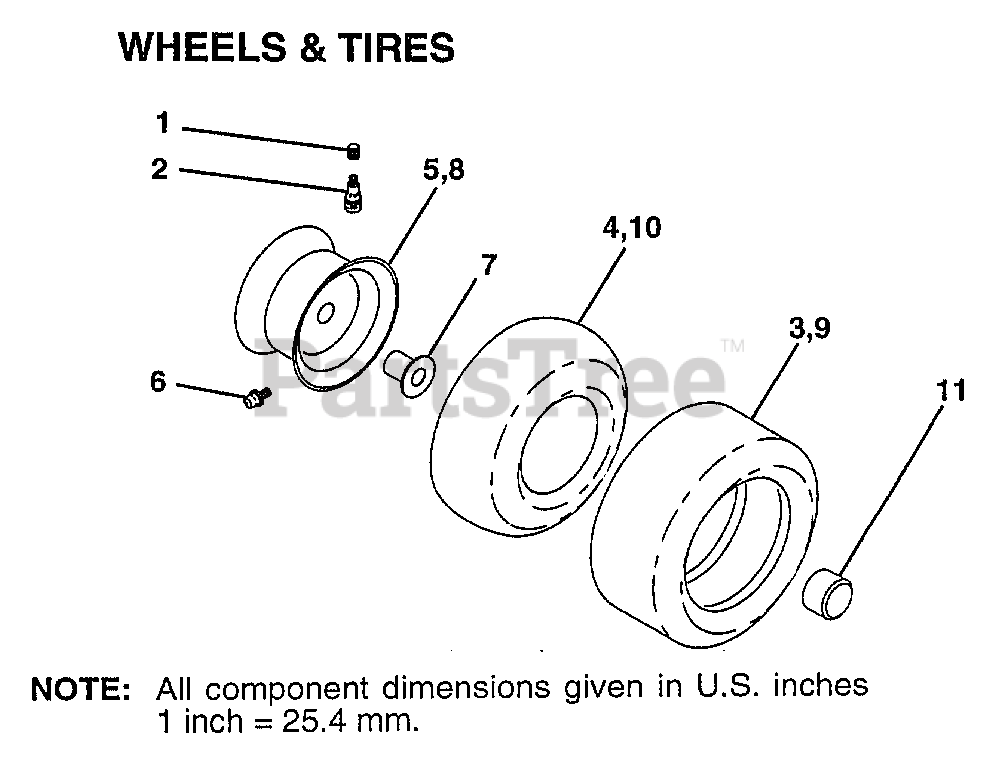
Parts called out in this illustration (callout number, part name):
1	VALVE CAP
2	VALVE STEM LT
4	TUBE.5.3/4.5/6
5	"RIM.ASM.6""FRONT"
6	FITTING LT
7	"FLANGE, BEARING"
8	"RIM.ASM.8""REAR"
10	TUBE.18X9.5-8
11	HUB CAP
